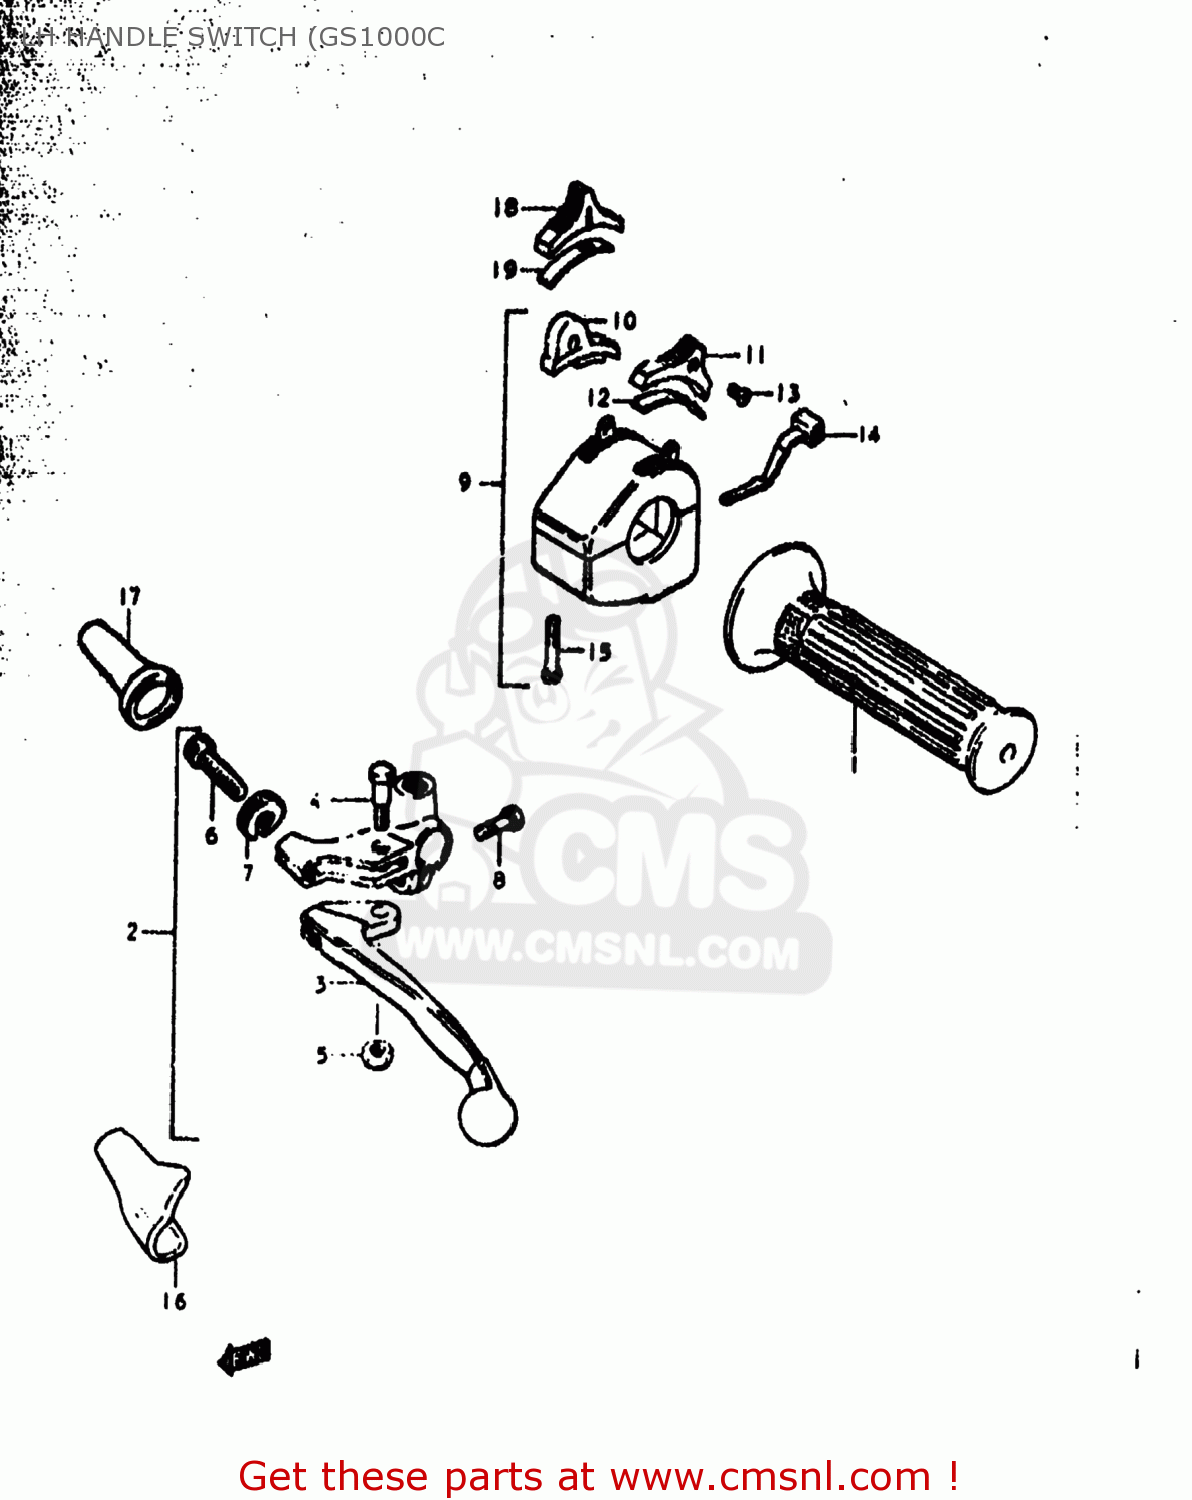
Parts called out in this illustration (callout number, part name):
1	GRIP,LEFT
2	LEVER ASSEMBLY
3	LEVER,CLUTCH
4	BOLT,LEVER PIVOT
5	NUT 6MM
6	ADJUSTER,CABLE
7	NUT,CABLE ADJUSTER
8	BOLT
9	SWITCH ASSEMBLY,HANDLE,LEFT
11	KNOB,HANDLE SWITCH
12	SPRING
13	SCREW
14	KNOB,TURN SIGNAL SWITCH
15	SCREW
16	COVER,CLUTCH LEVER
17	BOOT,CLUTCH CABLE
18	KNOB,HANDLE SWITCH
19	PLATE,SWITCH KNOB
